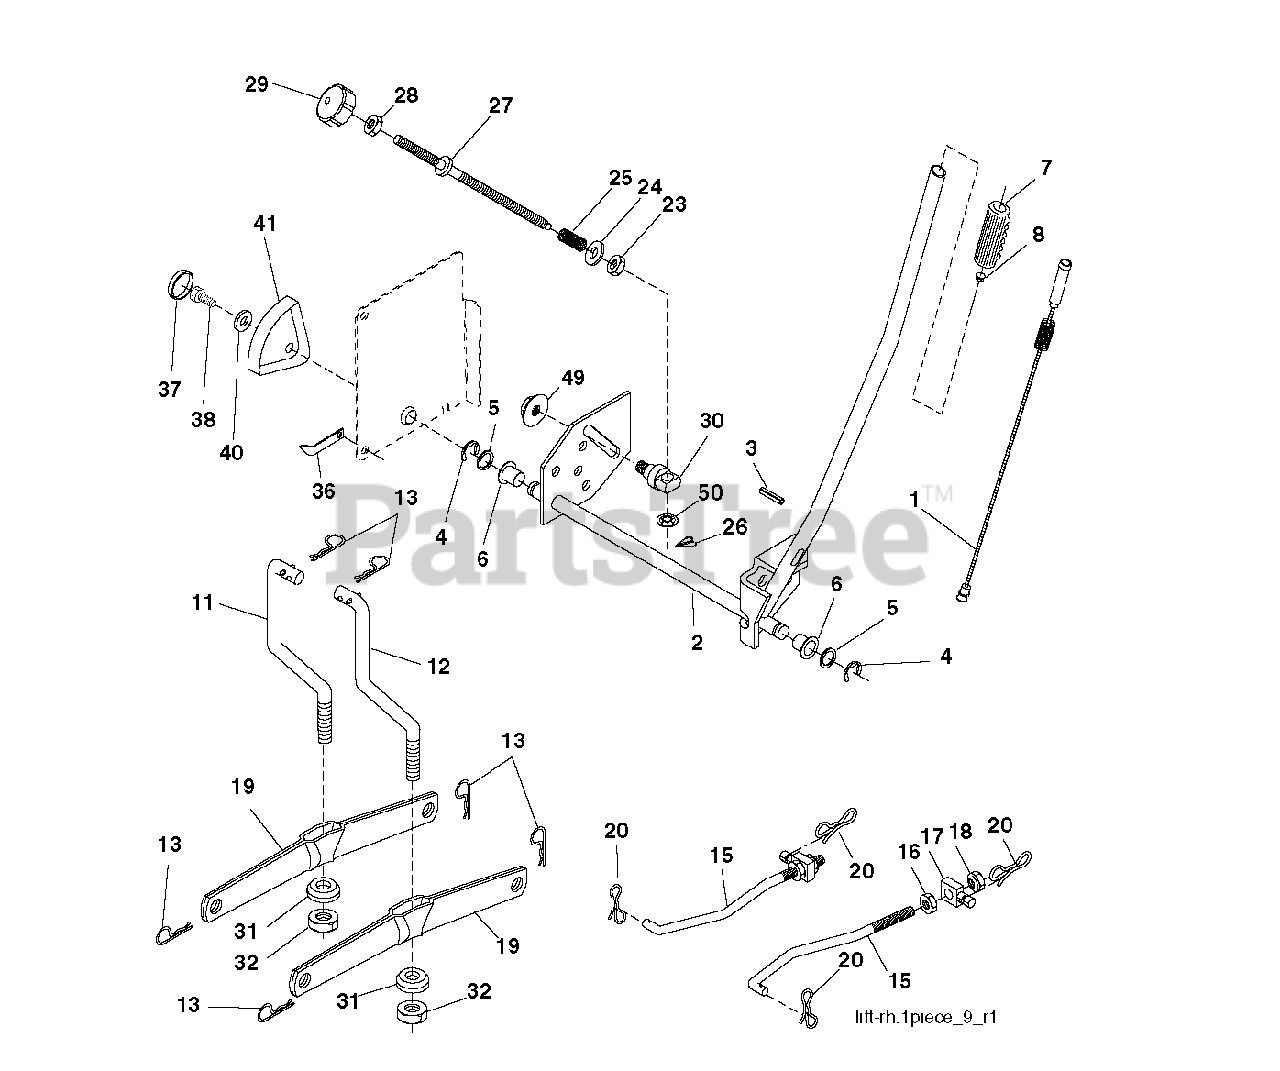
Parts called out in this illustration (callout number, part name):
1	PLUNGER.ASM.LIFT.LEVER.BLK.
2	SHAFT.ASM.LIFT.YT
3	PIN.GROOVE.5/16
4	RETAINING RING LT
6	BEARING.NYLON
7	GRIP HANDLE
8	REPL BY 532 12 59-25
11	LINK
12	LINK
13	Retainer Spring
15	LINK.SUSPENSION.FRONT
16	NUT.HEX.JAM.1/2-13
18	NUT.LK.W/WSH.1/2.
19	ARM.REAR.SUSPENSION
20	PIN.COTTER.7/16.BOW TI.
23	Special Nut
26	RETAINER CLIP
27	ROD ADJ LIFT
28	NUT
29	KNOB INF 3/8-16
31	BEARING.PIVOT.LIFT
32	NUT CROWNLOCK 3/8-24
36	POINTER, HEIGHT INDICATOR
38	SCREW 5/16-18X1
41	HEIGHT INDICATOR
49	NUT.HEX.FLANGE.3/8-16.LOCKNUT
50	NUT PUSH M
